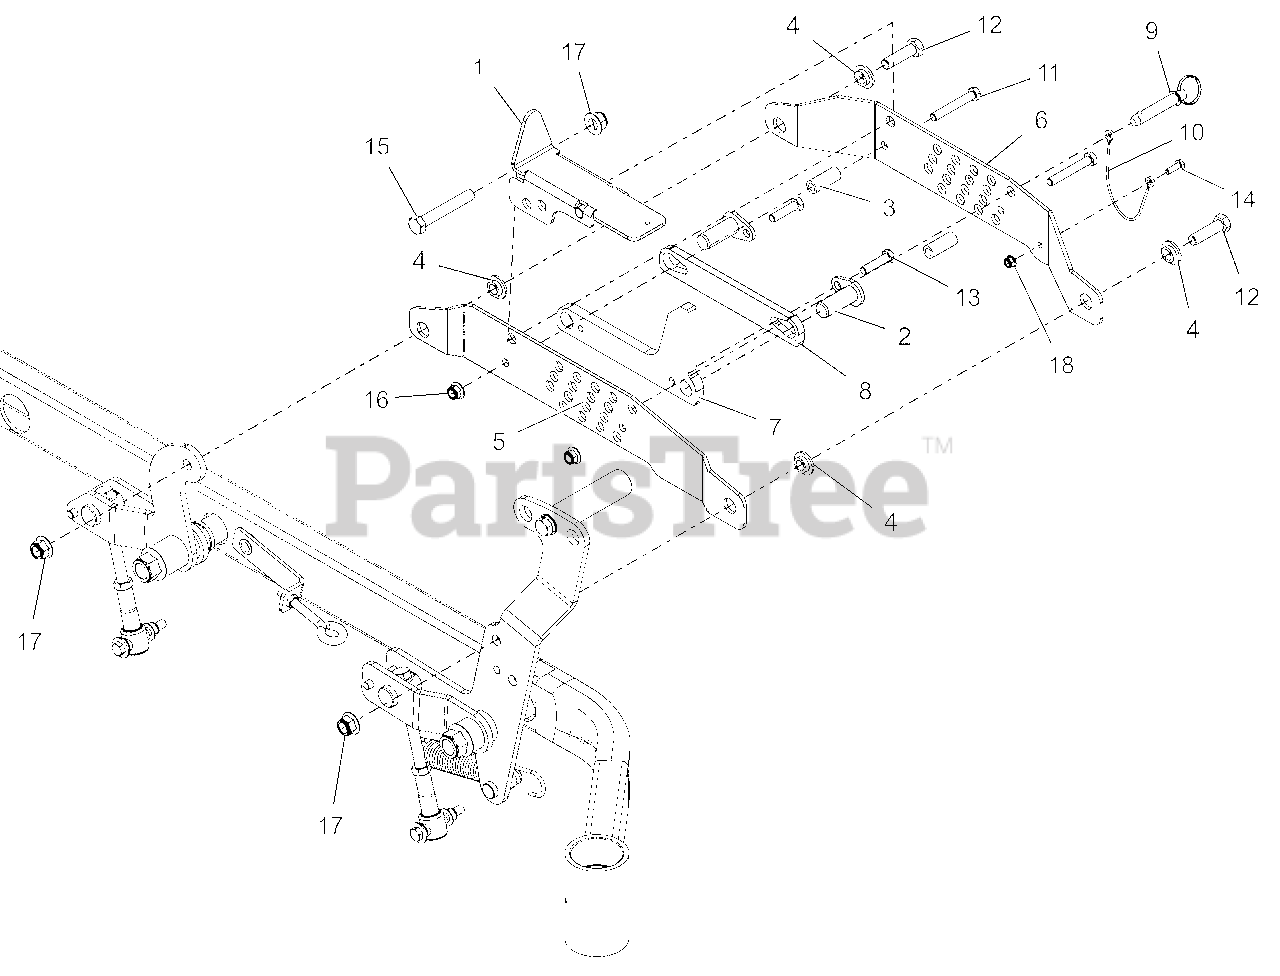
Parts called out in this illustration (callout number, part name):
1	MECHANICAL LOCK-UP WMT - BLACK
2	WLDMT, PIN HOC MOUNTING
3	SPACER, .375 X .625 X 1.54
4	BSHG-FLG .515X.750X.310X1.120
5	RH OTBRRD LIFT/CUT HT BRKT-BLK
6	RH INBRD LIFT/CUT HT BRKT- BLK
7	HOC STOP BRKT - BLK
8	HOC STOP SPACER - BLK
9	PIN, .50 X 2.00 USABLE LG BALL
10	CABLE, 12.0 LANYARD, NYLON
11	@BLT-HEX .38-16X2.50 GR5 YWZC
12	@BLT-HEX .50-13X1.75 GR5 YWZC
13	BLT,HEX .38-16X1.50 GR5 EP30
14	@BLT-HEX .25-20X.75 GR5 YWZC
15	@BLT-HEX .50-13X3.25 GR5 YWZC
16	@NUT-LK-NYL-FLG .38-16 YWZC
17	@NUT-LK-NYL-FLG .50-13 YWZC
18	@NUT-LK-NYL-FLG .25-20 YWZC
